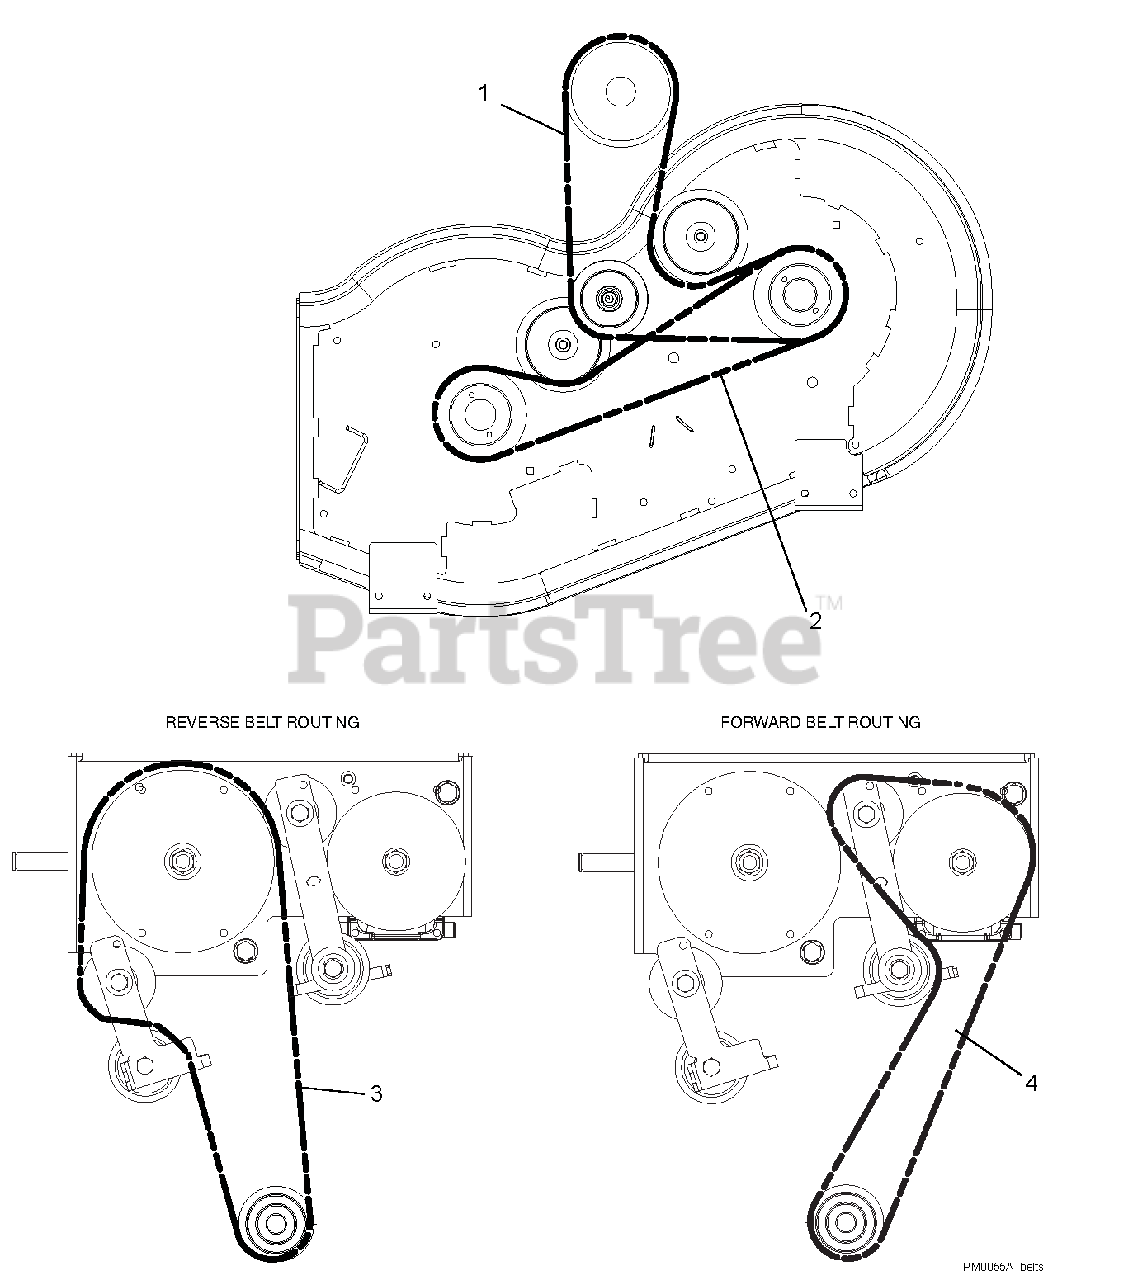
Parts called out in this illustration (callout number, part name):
1	V-BELT, HA WRAPPED
2	V-BELT, HA-WRAPPED
3	V-BELT, 3L-WRAPPED
4	V-BELT, 3L-WRAPPED
